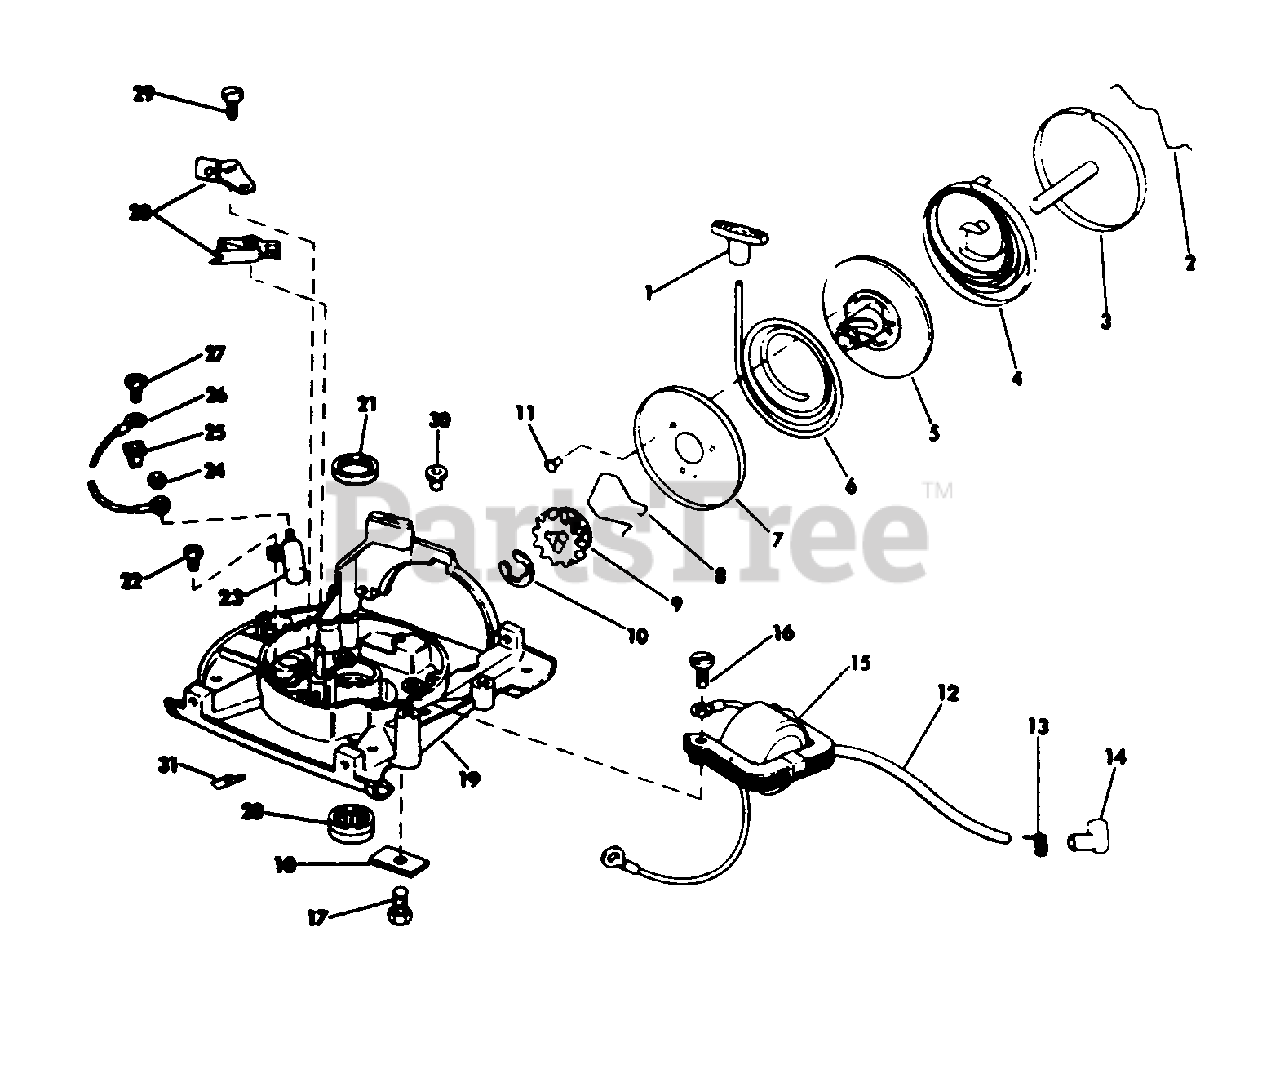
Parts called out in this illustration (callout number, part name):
1	Handle-Starter
2	Spring-Starter Rope Retainer
3	Spring-Cup & Pin Assembly
4	Spring-Starter
5	Pulley-Starter
6	Rope-Starter
7	Plate-Starter Pulley
8	Spring-Starter Pinion
9	Pinion-Starter
10	Retainer-Push-On
11	Screw-Thrd. Cutting, Starter
12	High Tension Lead Assy.
13	Terminal-Spring
14	Cover-Rubber
15	Coil & Lamination Assembly
16	Screw-Lamination Mounting
17	Screw-Starter Attaching
18	Clamp-Starter Pin
19	Arm. Pl., Brg. & Oil Seal Assy.
20	Bearing
21	Oil Seal
22	Screw-Condenser Mtg.
23	Condenser & Nut Assembly
25	Grommet-Nylon
26	Terminal & Lead Assembly
27	Screw-Shut-Off Switch
28	Breaker Base & Arm Assembly
29	Screw-Breaker Base
30	Grommet
